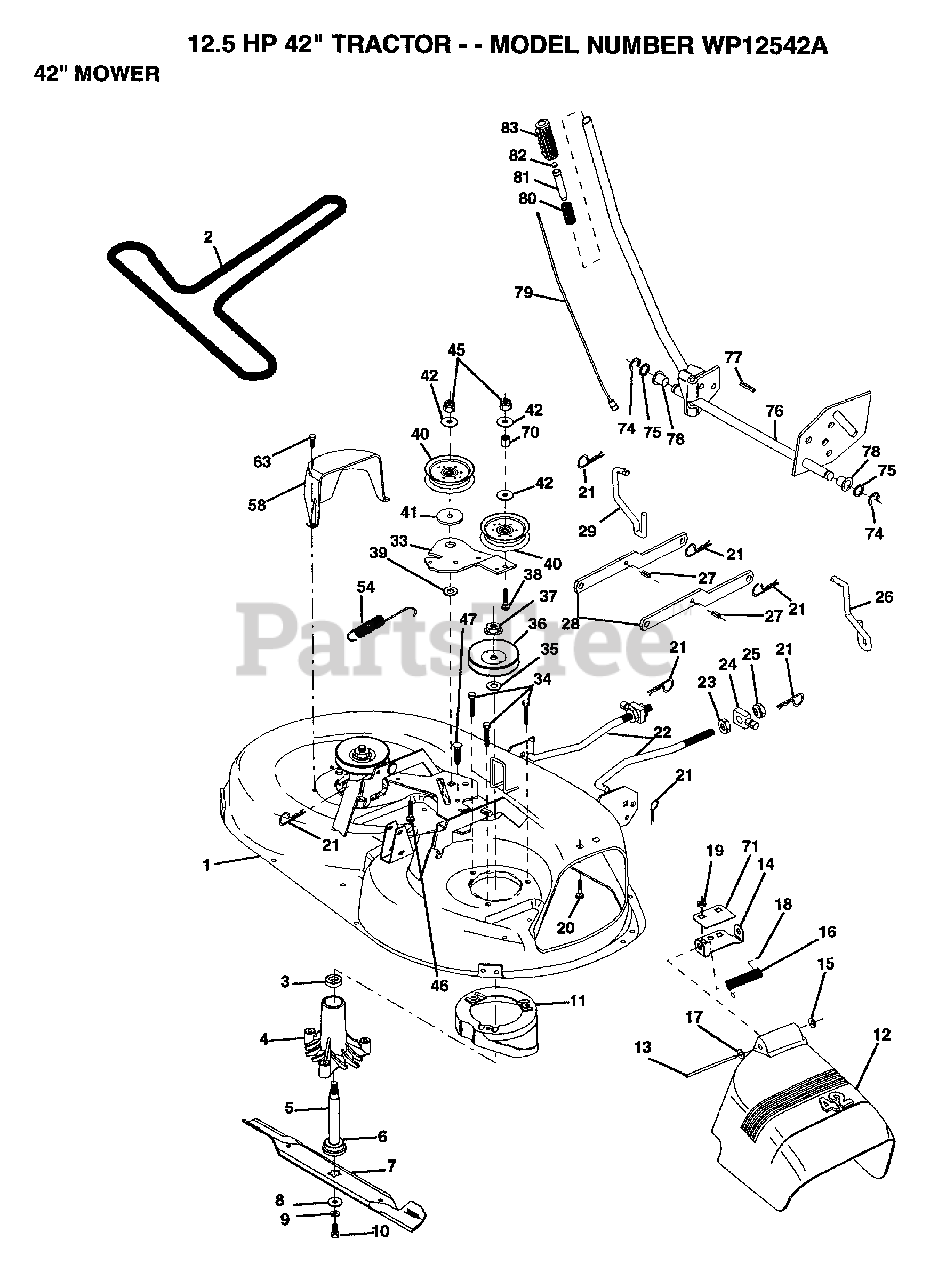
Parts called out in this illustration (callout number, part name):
2	BELT-V.92.4.MWR
3	BEARING
4	HSG ASM MANDREL
6	BEARING.BALL
8	WASHER BLADE
10	BLADE BOLT
12	DEFLECTOR.SHIELD
13	HINGE ROD
14	DEFLECTOR BRKT
15	NUT PUSH M
16	SPRING TORSION
17	WASHER
18	CAP-SLEEVE LT
20	BOLT
22	LINK.FRONT
23	NUT
24	TRUNION
25	NUT.LK.W/WSH.1/2.
26	LIFT LINK RH
27	"PIN,SPRING"
29	LINK LIFT LH
33	IDLER ARM
35	WASHER
38	BOLT
39	HARDENED WASHER
40	FLAT IDLER PULLEY
41	SPACER RETAINER
42	WASHER
46	BOLT
47	XMAS TREE FASTNER
54	SPRING.EXTENSION
63	SCREW LT
71	STIFFENER BRKT
75	WASHER
76	LIFT SHAFT ASM
77	PIN-GROOVE LT
78	NYLON BEARING
83	GRIP
